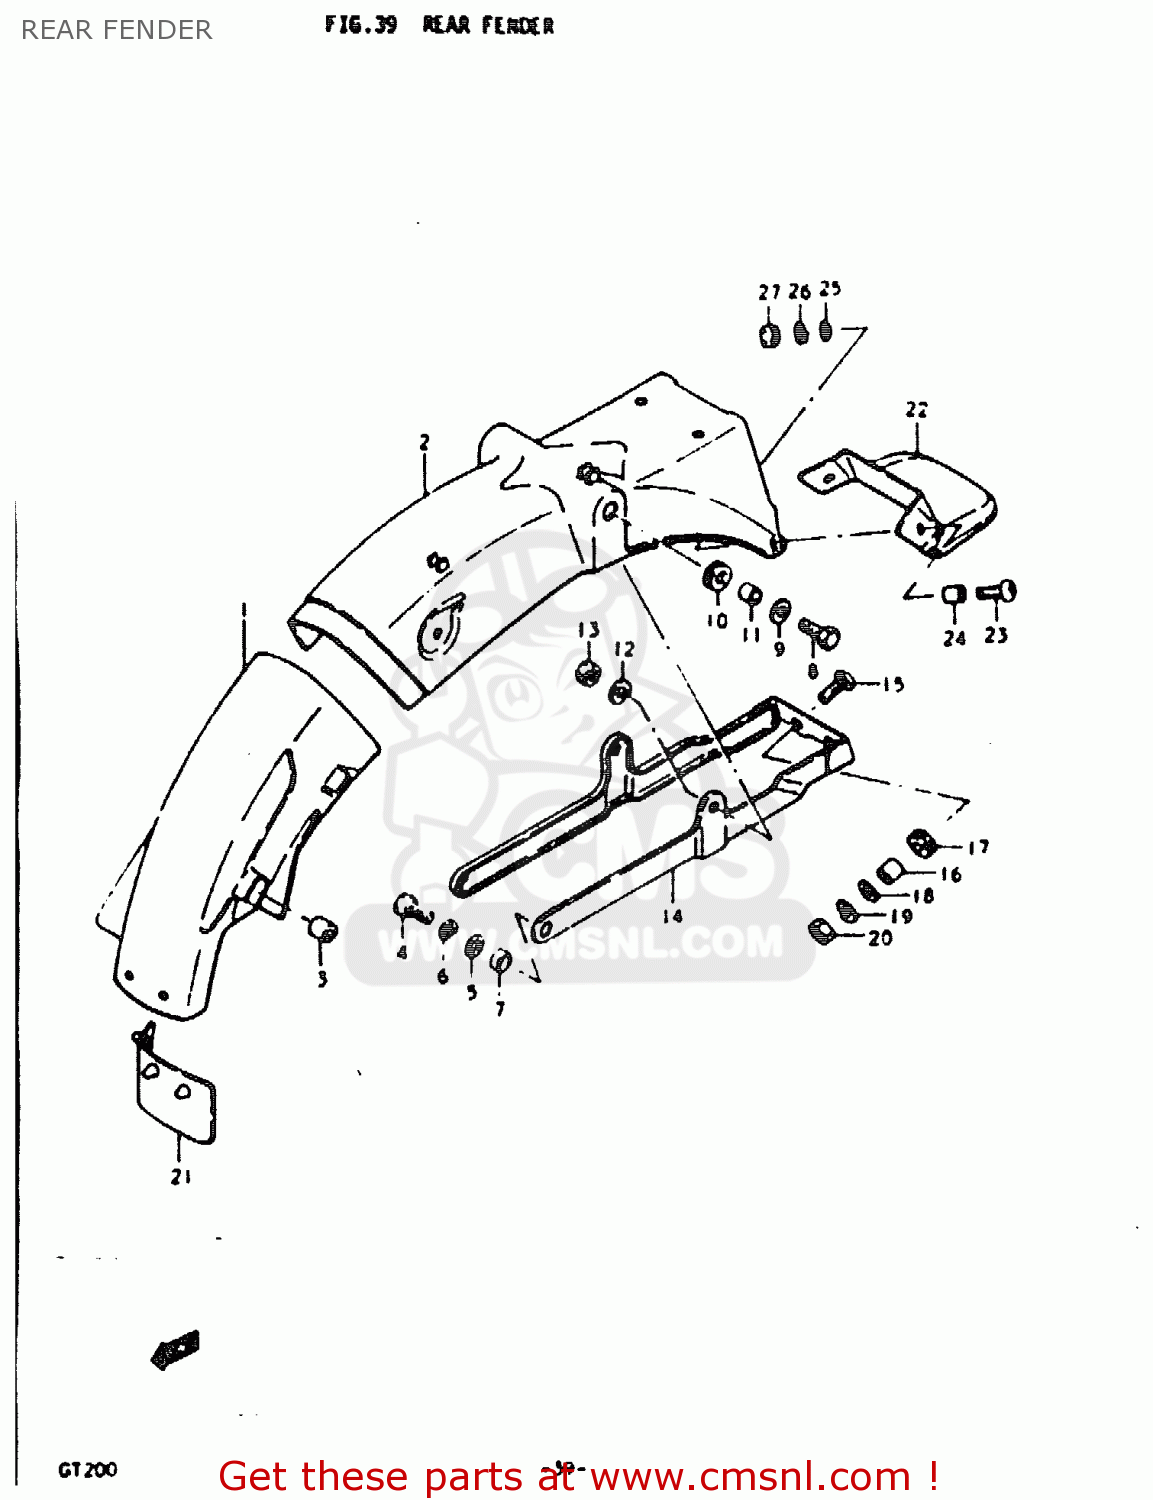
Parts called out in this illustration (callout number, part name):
1	BODY, REAR FENDER FRONT
2	BODY, REAR FENDER REAR
3	CUSHION
4	BOLT
5	WASHER
6	LOCK WASHER
7	SPACER(8.5X12X2.5)
8	BOLT (8X30)
9	WASHER
10	CUSHION
11	SPACER (8.2X12X7.5)
12	LOCK WASHER
13	NUT
14	REINFORCEMENT, REAR FENDER
15	SCREW
16	SPACER (6.1X9X9)
17	CUSHION
18	WASHER(6,5X22X1.6)
19	LOCK WASHER
20	NUT
21	MUD GUARD,REAR FENDER
22	EXTENSION,REAR FENDER
23	SCREW (6X15)
24	SPACER(6.2X8.3X5.7)
25	WASHER(6.5X18X1)
26	LOCK WASHER
27	NUT
